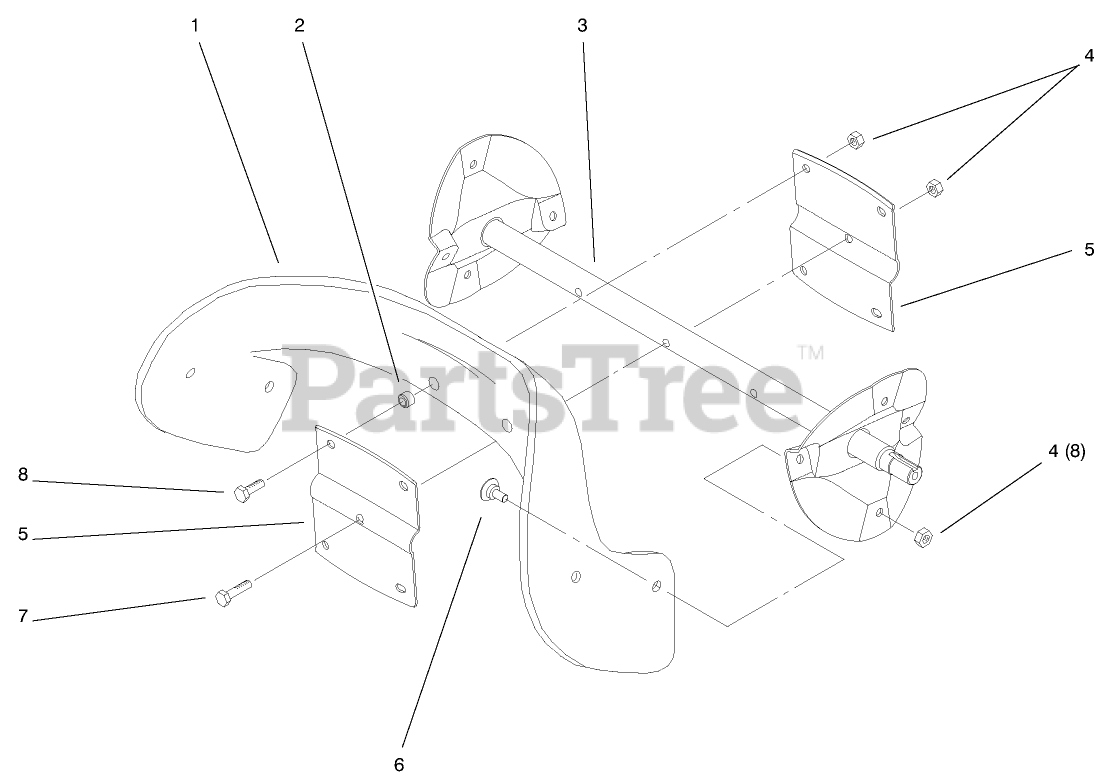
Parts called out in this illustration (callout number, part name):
1	BLADE-ROTOR
2	SPACER-BLADE, ROTOR
4	NUT-LOCK, NI
5	HALF-ROTOR
6	SCREW
7	SCREW-HH
8	SCREW-HH
